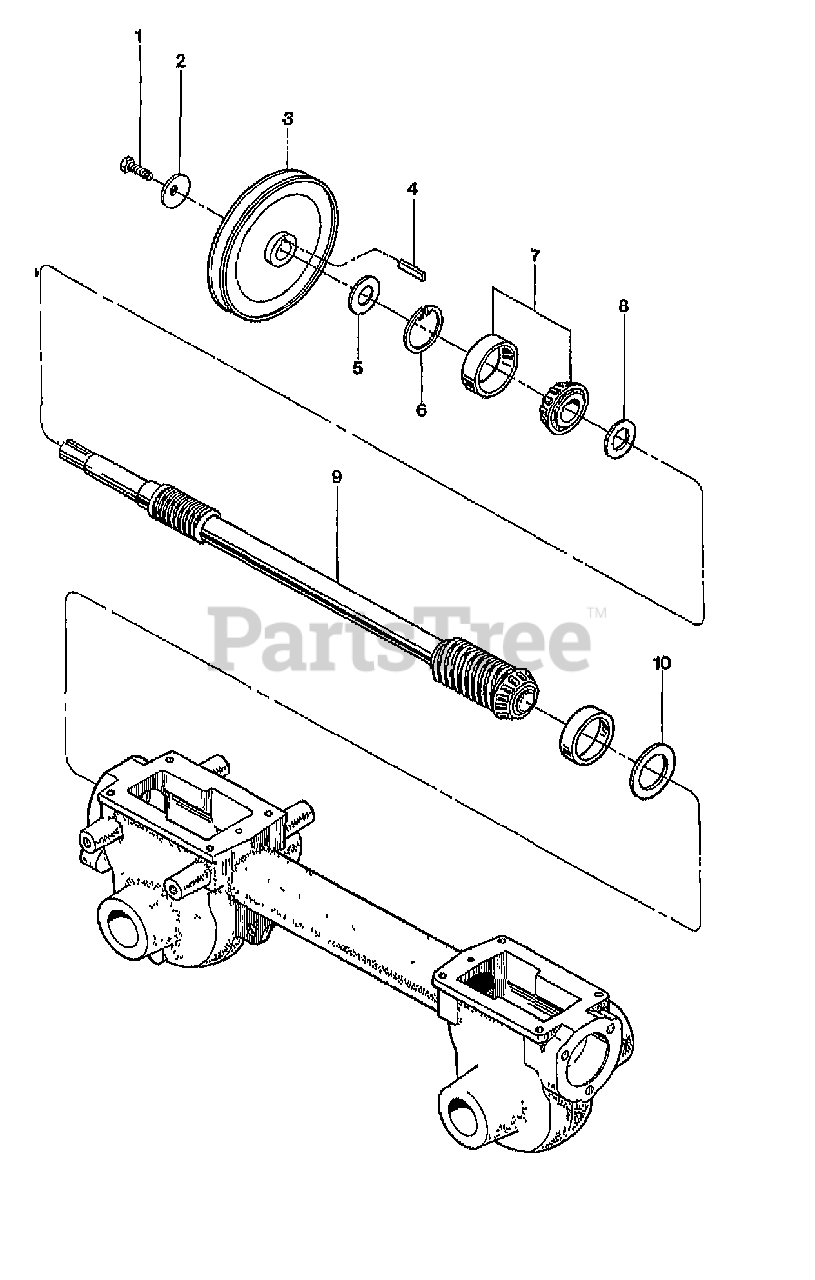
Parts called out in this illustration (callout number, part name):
1	SCR-HH 5/16-24X.75 G5 ZP
2	WASHER-.827X.331X.098
3	PULLEY-TRANSMISSION
4	KEY-.188 SQX1.0
5	WASHER-SHLDR HARDENED
6	RING-RETAINING 5000-181
7	KIT-BRG CONE&RACE-DRIVESHAFT
8	WASHER-#1.25X.75X.06
9	DRIVESHAFT-MACH
9	ASSM-DRIVESHAFT TUFFY {12155}
10	SHIM-1.75X1.5X.01 AS REQ'D
10	SHIM-1.75X1.5X.03 AS REQ'D
10	SHIM-1.75X1.5X.005 AS REQ'D
10	SHIM-1.75X1.5X.062 AS REQ'D
10	SHIM SET-DRIVESHAFT-HORSE
